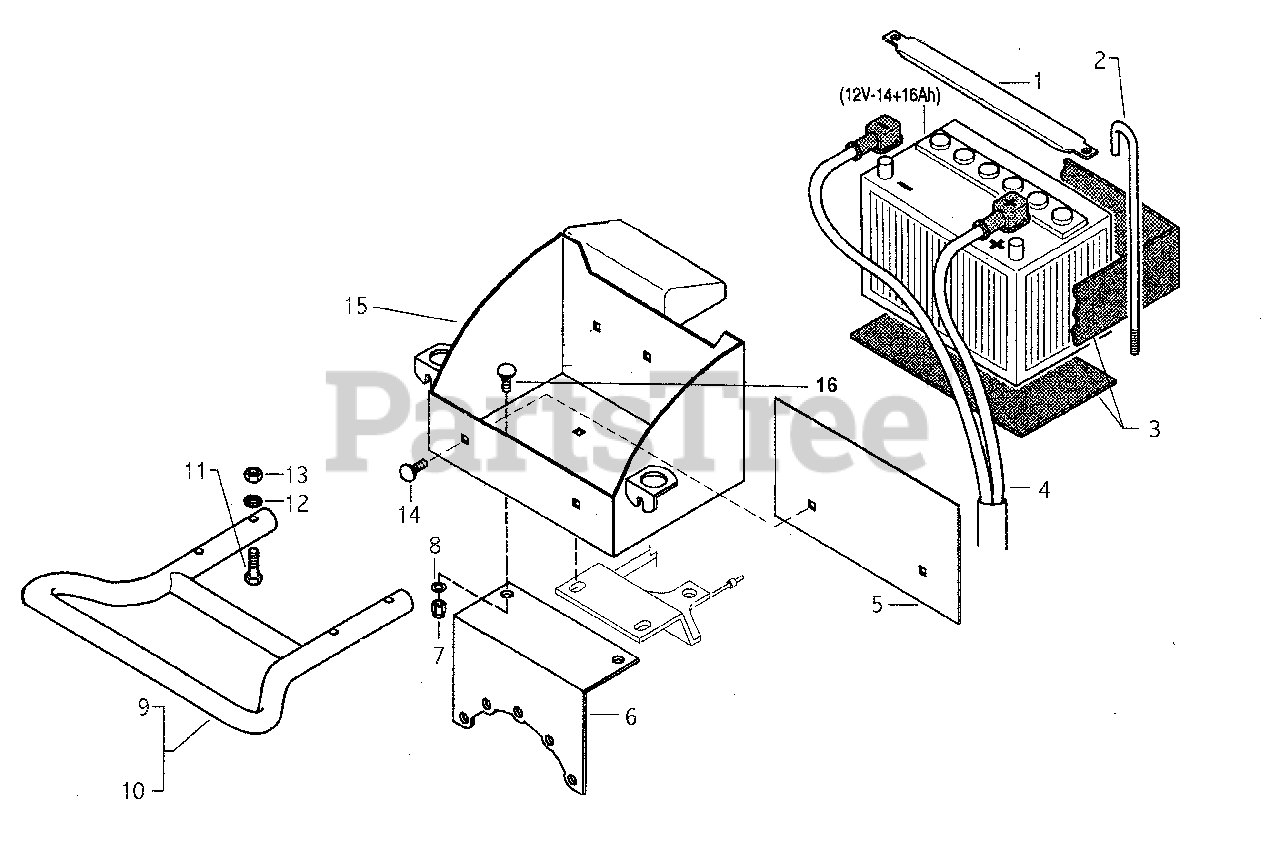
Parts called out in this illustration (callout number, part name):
1	BATTERY BRACKET
2	BATTERY TIEROD
3	BATTERY PADS
4	ELECTRIC START CABLES
9	BUMPER, INTEK ENGINES
10	BUMPER, KOHLER CS PRO 8.5, 12HP
11	SCREW M8X60
12	FLAT WASHER 8.4
13	NUT, SELF LOCKING M8
15	BATTERY SUPPORT KOHLER CS PRO
